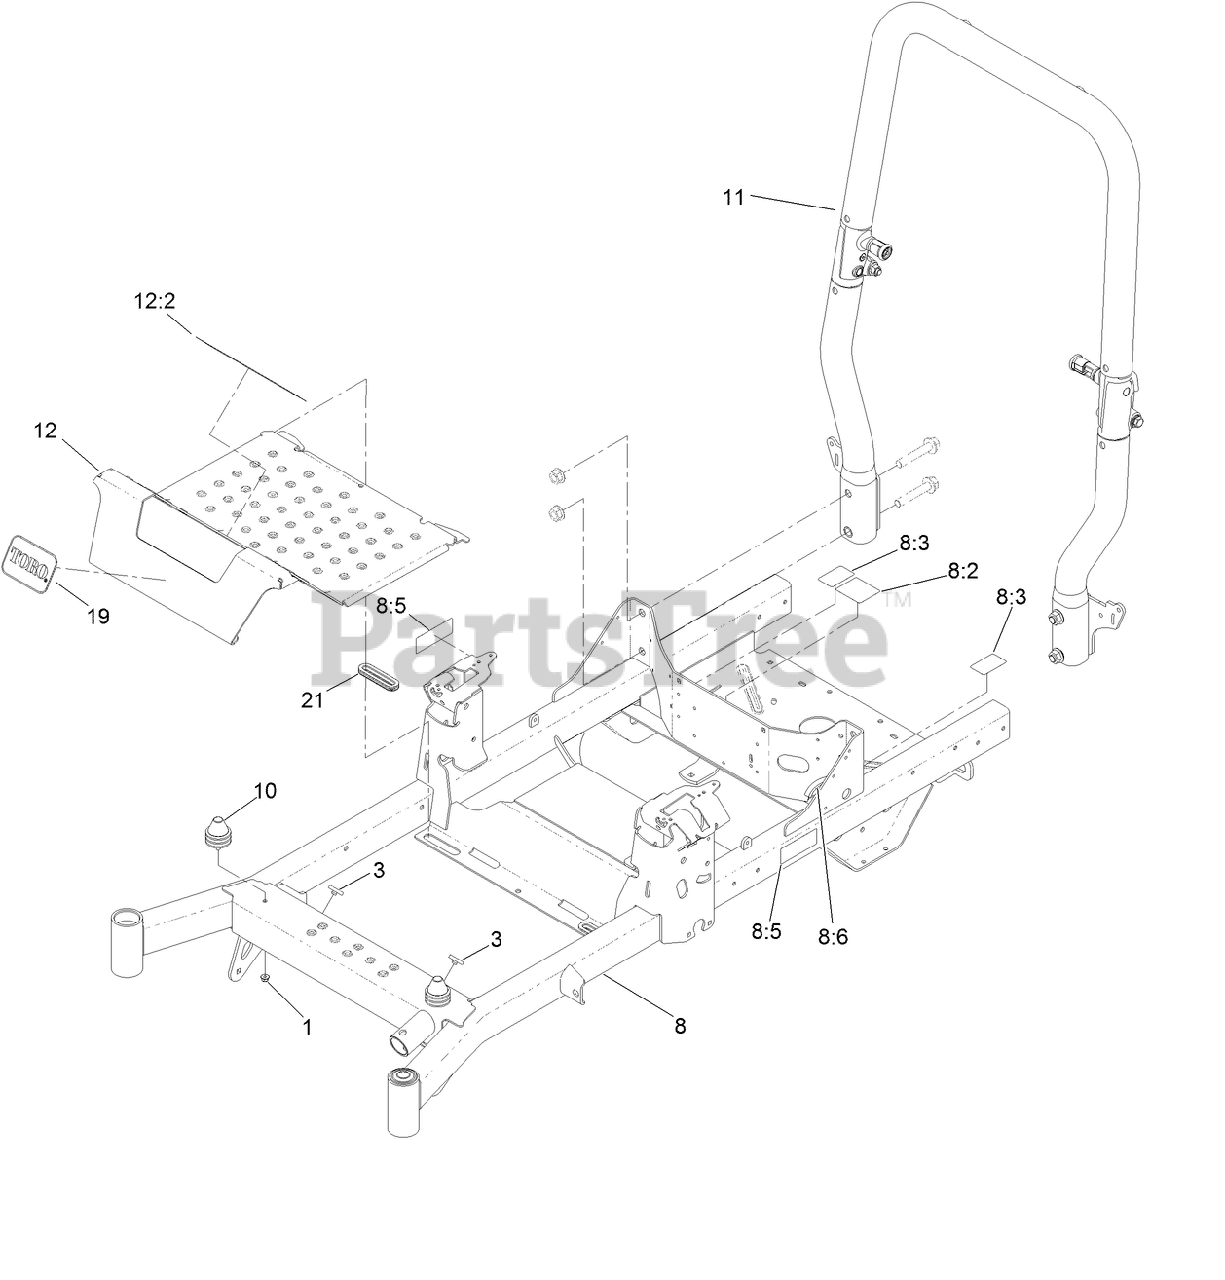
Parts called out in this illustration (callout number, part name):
1	NUT-HF, NI
3	BUMPER-PUSH-IN, RUBBER
8	FRAME ASM
8:2	DECAL-ROUTING, BELT
8:3	DECAL-RELEASE, DRIVE
8:5	DECAL-WARNING
8:6	STRIP-SEAL
10	ISOLATOR
11	ROPS ASM
12	PAN-FLOOR
12:2	DECAL-DANGER
19	DECAL
21	GROMMET-RUBBER
